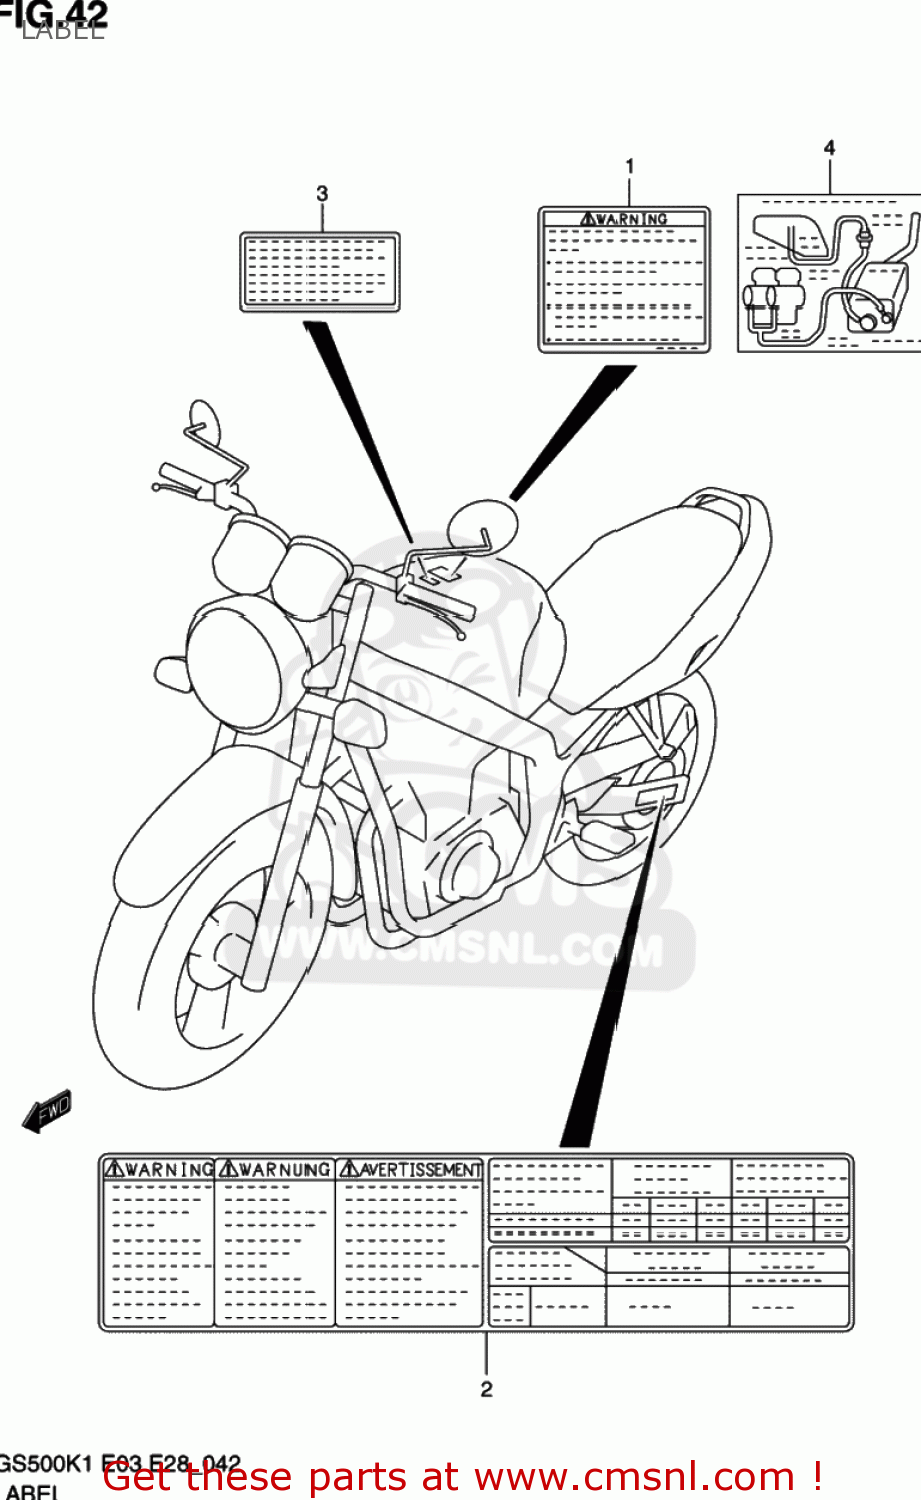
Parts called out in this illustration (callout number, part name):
1	LABEL,GENERAL WARNING
2	LABEL, TIRE INFORMATION
3	LABEL,MANUAL NOTICE
4	LABEL,VACUUM HOSE ROUTING
5	MANUAL,OWNER'S
